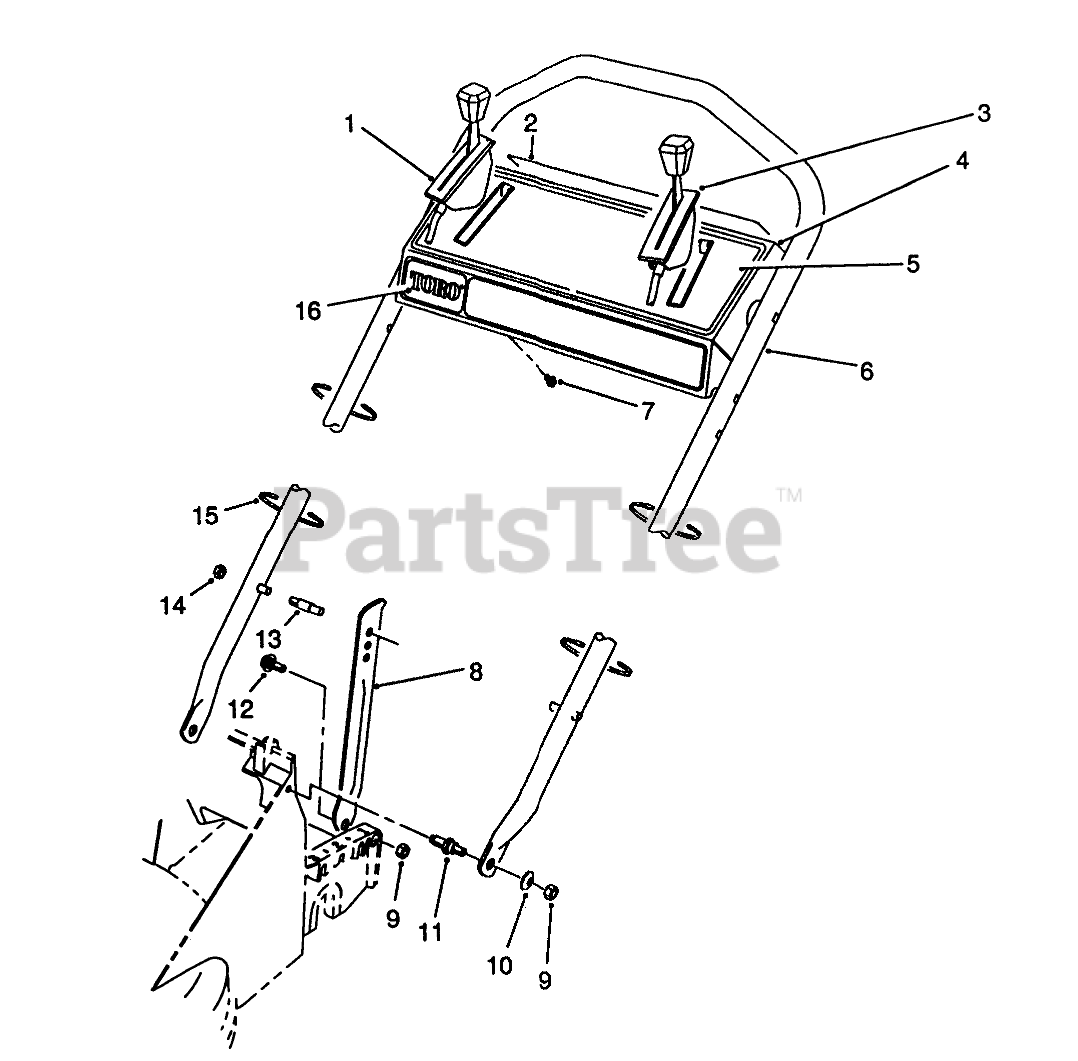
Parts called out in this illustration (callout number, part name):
1	Control-Ground Speed Bend Type #3 Sheath Lg. 51-1/4" Wire Lg. 2-1/8"
2	DECAL-PANEL, DANGER
3	ControI-Throttle Bend Type #2 Sheath Lg. 44-3/4" Wire Lg. 2-1/2"
4	Control Panel Assembly (Incl. Ref. #2, 5 & 16)
5	DECAL - INSTRUCTION
6	HANDLE
7	SCREW-HWHTF
8	HANDLE LATCH
9	NUT-LOCK, NI
10	WASHER-PLAIN
11	SCREW - SHOULDER STUD
12	SCREW - SHOULDER
13	HANDLE PIN
14	NUT-LOCK, NI
15	TIE-CABLE
16	DECAL - TORO PANEL
